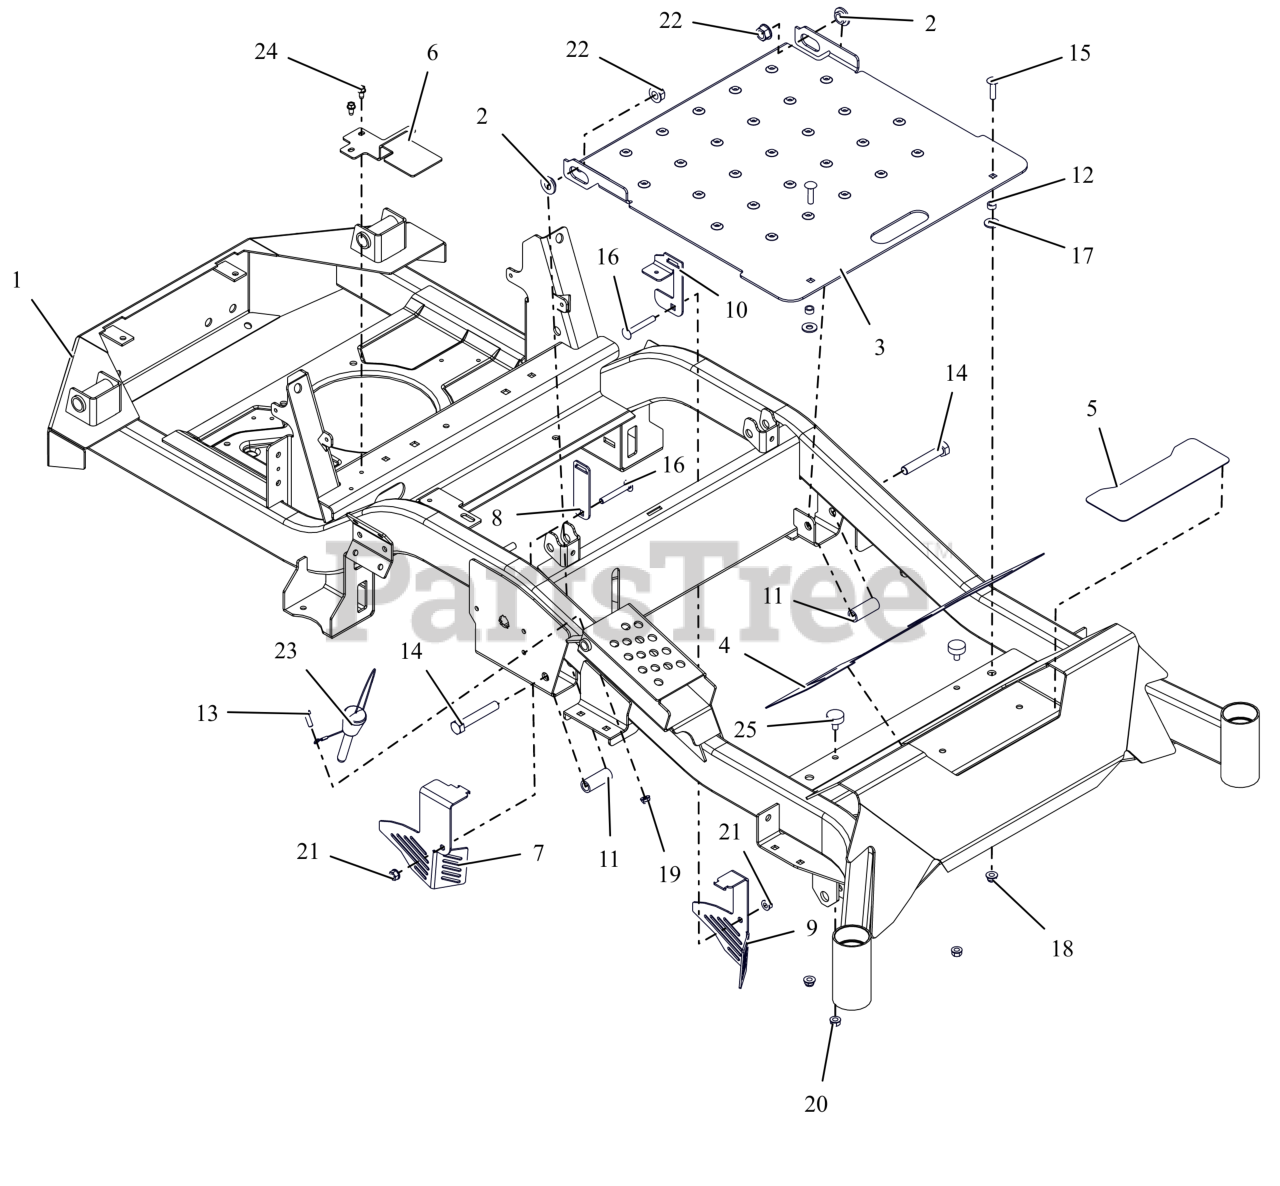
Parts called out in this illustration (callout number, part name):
1	APEX,44-52 FRAME W/SAFETY DECA
2	BSHG-FLG .515X.750X.395X1.120
3	PANEL, ACCESS
4	GRIP, FRONT
5	GRIP, STEP
6	GUARD, TRANSAXLE FAN RH (BLACK)
7	GUARD, TRANSAXLE FAN - RH
8	BRKT, TRANSAXLE FAN GUARD
9	BRKT, TRANSAXLE FAN GUARD-LH
10	MOUNT, TRANSAXLE GUARD
11	SPACER, .515X.75X1.83
12	BSHG-SLV .344 X .500 X .260
13	BLT, HEX .25-20X.75 G5 ZCC
14	BLT, HEX .50-13X3.00 G5 ZCC
15	BLT, RHSSN.31-18X1.25 G5 ZCC
16	BLT, RHSSN.31-18X2.25 G5 ZCC
17	WSHR,FLT .375X.875X.083 ZCC
18	NUT,LK-NYL-FLG .31-18 G5ZC120
19	NUT,NYL-FLG .25-20 GF ZCC
20	NUT,SPNLK-FLG .31-18 G5 ZCC
21	NUT,LK-CTR-FLG .31-18 GF ZCC
22	NUT-LK-TOP-FLG .500-13 GF ZCC
23	PIN, MAGNETIC .50X2.50
24	SCR-TAP .25-20X.50 HWH ZCC
25	BUMPER, RUBBER
